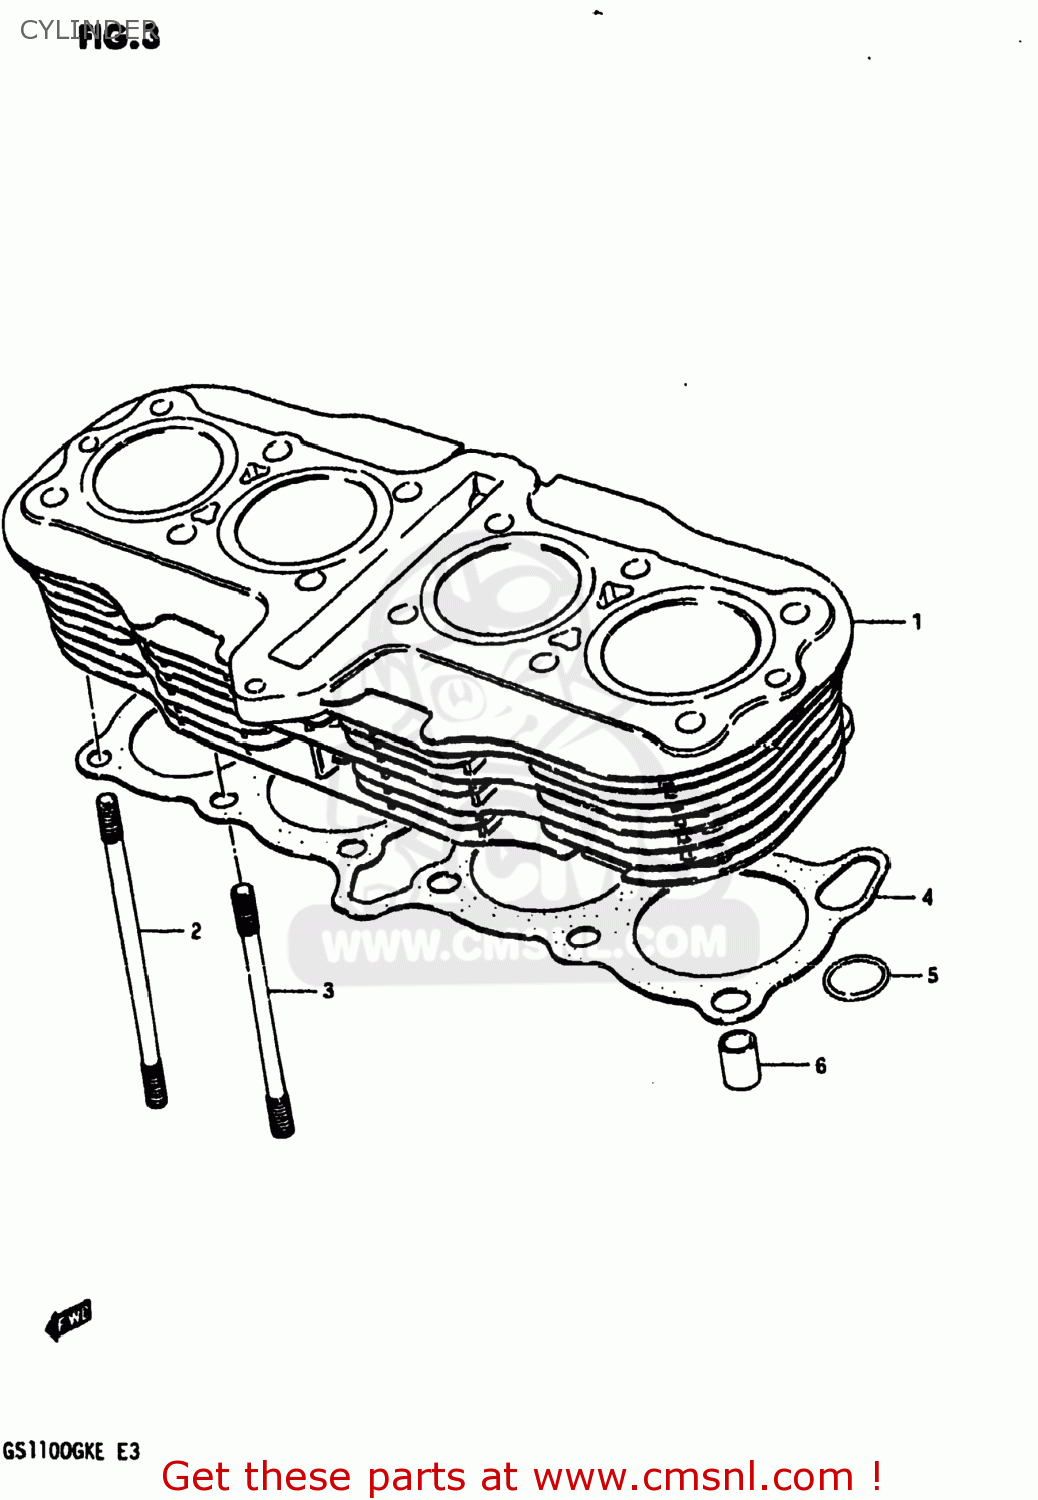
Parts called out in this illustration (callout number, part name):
1	CYLINDER
2	BOLT,STUD
3	STUD
4	GASKET,CYLINDER (MCA)
5	O RING(D:3.5)
6	PIN
